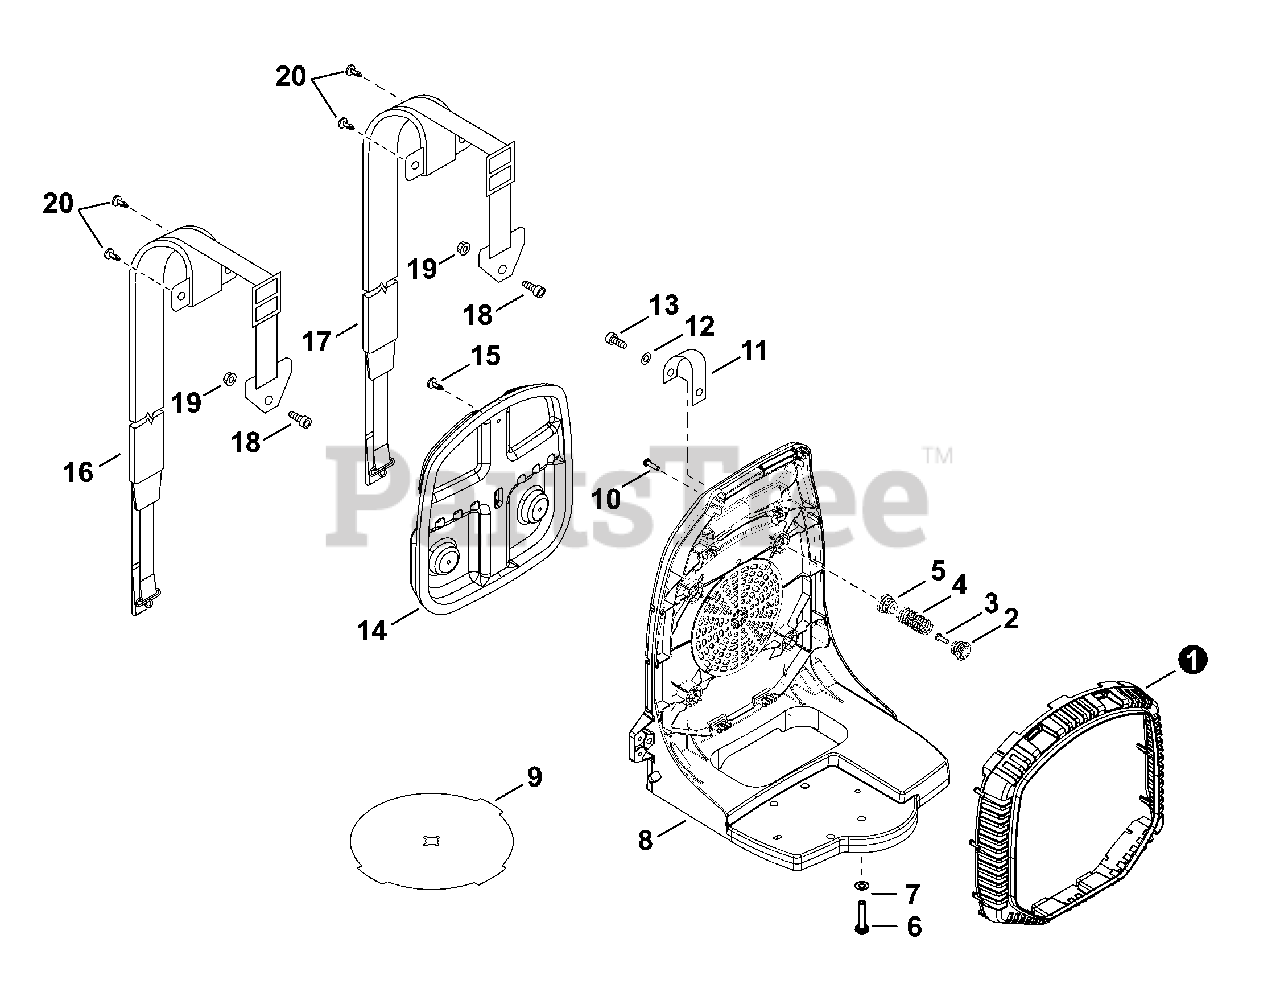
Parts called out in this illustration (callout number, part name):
1	GUARD, DEBRIS
2	HOLDER, SPRING
3	SCREW - 5×16
5	HOLDER, SPRING
6	SCREW - 5×25
7	WASHER - 5
8	FRAME, BACKPACK
9	INSERT, COLD WEATHER
10	SCREW - 5×20
11	STRAP, SAFETY
12	WASHER - 5
13	SCREW - 5×20
14	CUSHION, BACKPACK
16	HARNESS ASSY - LEFT
17	HARNESS ASSY - RIGHT
18	SCREW - 5×30
19	LOCKNUT - 5
